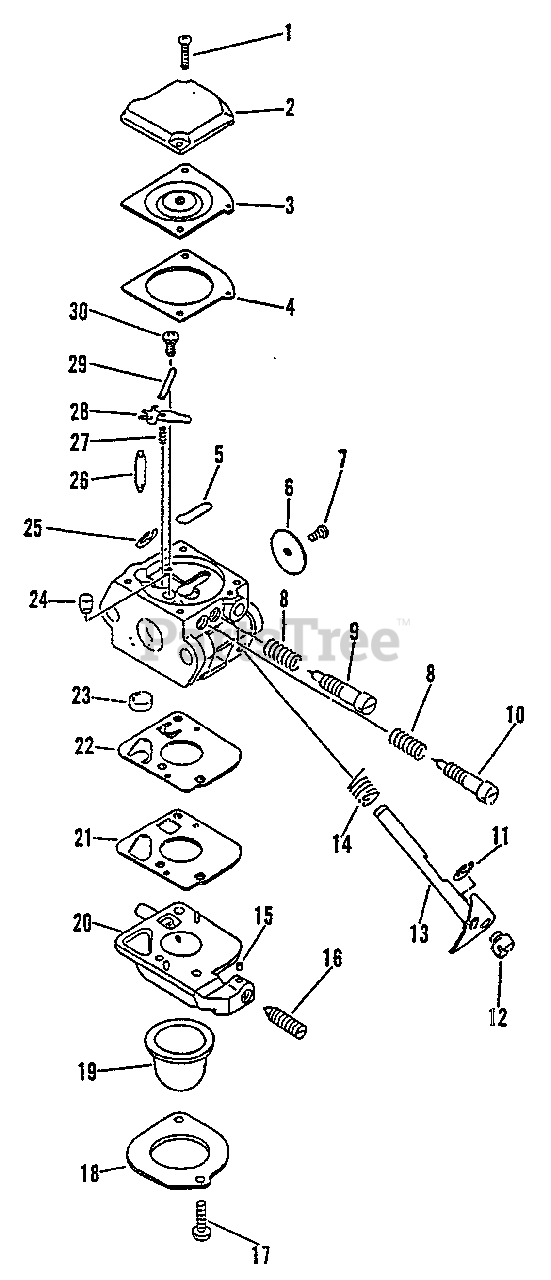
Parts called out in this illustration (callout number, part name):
2	COVER, METERING
3	DIAPHRAGM
4	GASKET, DIAPHRAGM
5	PLUG, WELCH
6	VALVE, THROTTLE
9	NEEDLE - HIGH SPEED
10	NEEDLE - LOW SPEED
11	RING, RETAINING
13	SHAFT, THROTTLE
14	SPRING, RETURN
15	PIECE, FRICTION
16	SCREW, IDLE ADJUST
17	SCREW, RETAINER
18	RETAINER, PURGE BULB
19	BULB, PURGE
20	BASE, PURGE
21	GASKET, PUMP
22	DIAPHRAGM, PUMP
23	STRAINER
24	NOZZLE, CHECK VALVE
25	RING, RETAINING
26	VALVE, NEEDLE
27	SPRING
28	LEVER, METERING
29	PIN, METERING LEVER
30	SCREW, METERING LEVER PIN
